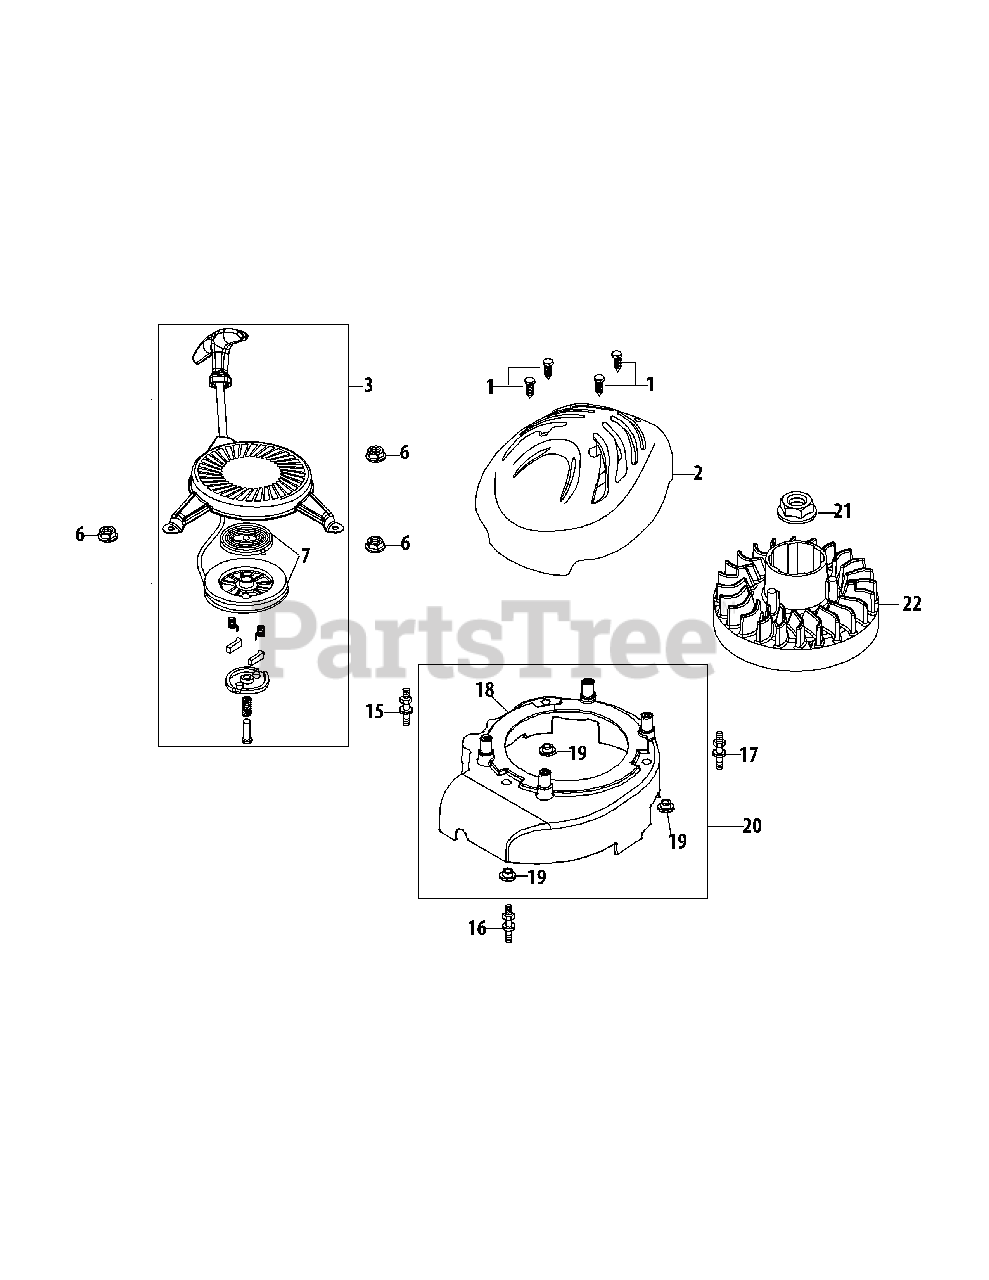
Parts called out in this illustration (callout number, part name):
1	Screw, #12-16 X 1.00"
2	Outer Shroud (Model Specific)
3	Recoil Starter Assembly
6	Nut M6X10Mm
7	Recoil Spring
15	Stud Left/Black/Ye Zinc
16	Stud Front/Unmarked/Ye Zinc
17	Stud Right/White/Ye Zinc
18	Inner Shroud
19	Engine Shroud Spacer
20	Inner Shroud Assembly
21	Flywheel Nut M14
